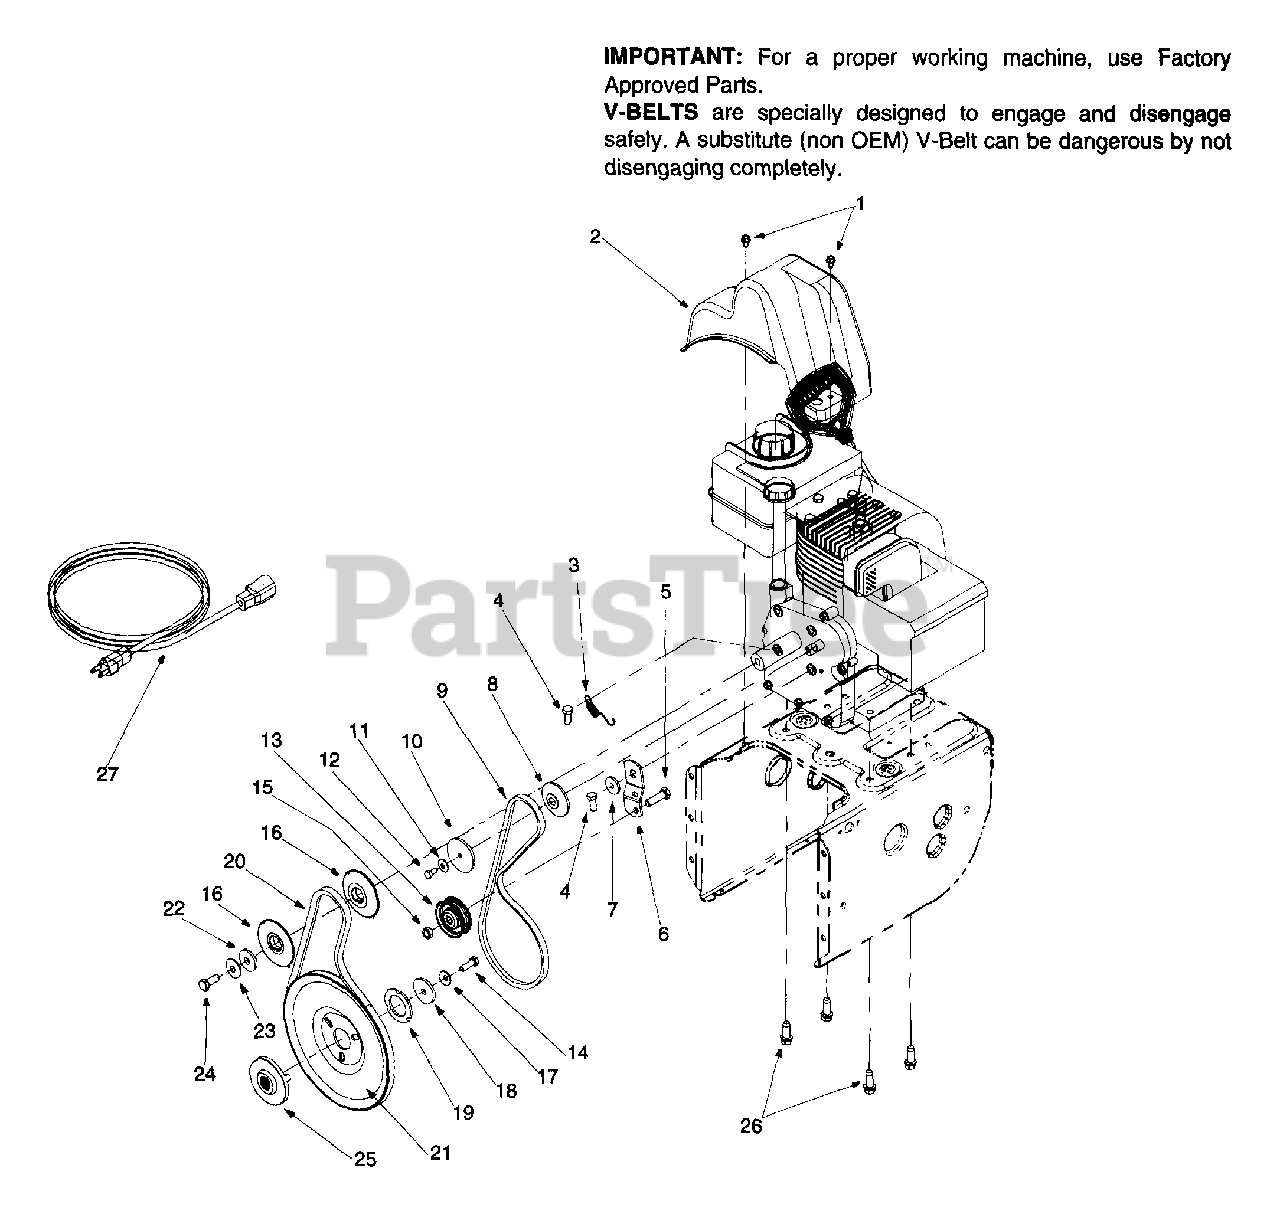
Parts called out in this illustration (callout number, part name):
1	Hex Washer Screw 1/4-20 x .5
2	Belt Cover
3	Extension Spring
4	Hex Screw 5/16-24 x .75
5	Hex Cap Screw 3/8-16 x 1.25
8	Pulley Half
9	V-Belt
10	Pulley Half
11	Bell Washer
12	Hex Cap Screw 1/4-28 x .50
13	Flat Idler
14	Lock Cap Screw 5/16-24
15	Lock Jam Nut 3/8-16
16	Pulley Half
17	Bell Washer
18	Flat Washer
19	Washer
20	Belt
21	Auger Pulley
22	Flat Washer
23	Bell Washer
24	Hex Cap Screw 3/8-24
25	Pulley
26	Hex Washer Screw 3/8-16 x 1.0
27	Extension Cord
